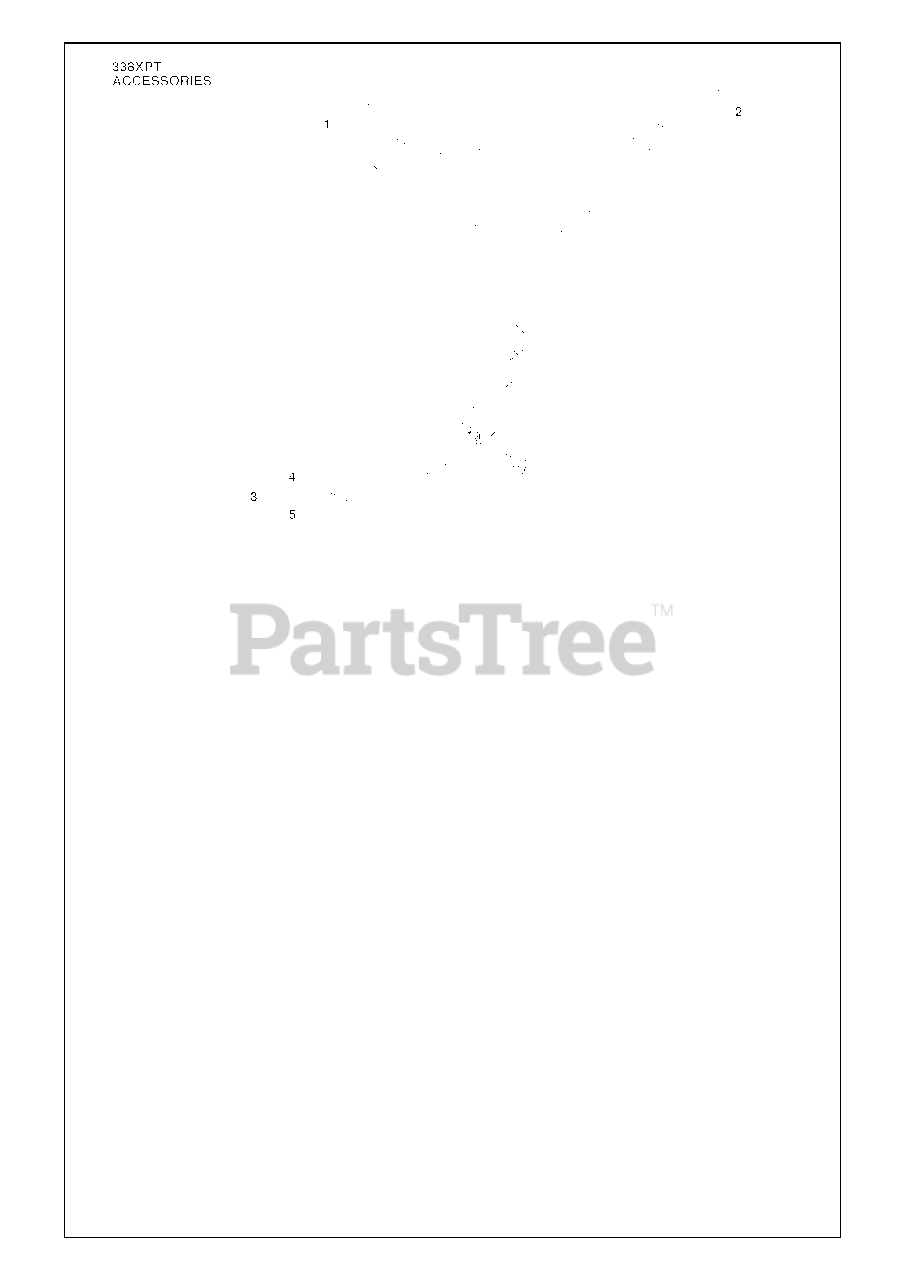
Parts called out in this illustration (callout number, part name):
1	Scabbard, 13"-16"
2	COMBI TOOL
3	WINTER COVER ASSY
4	Winter Cover
